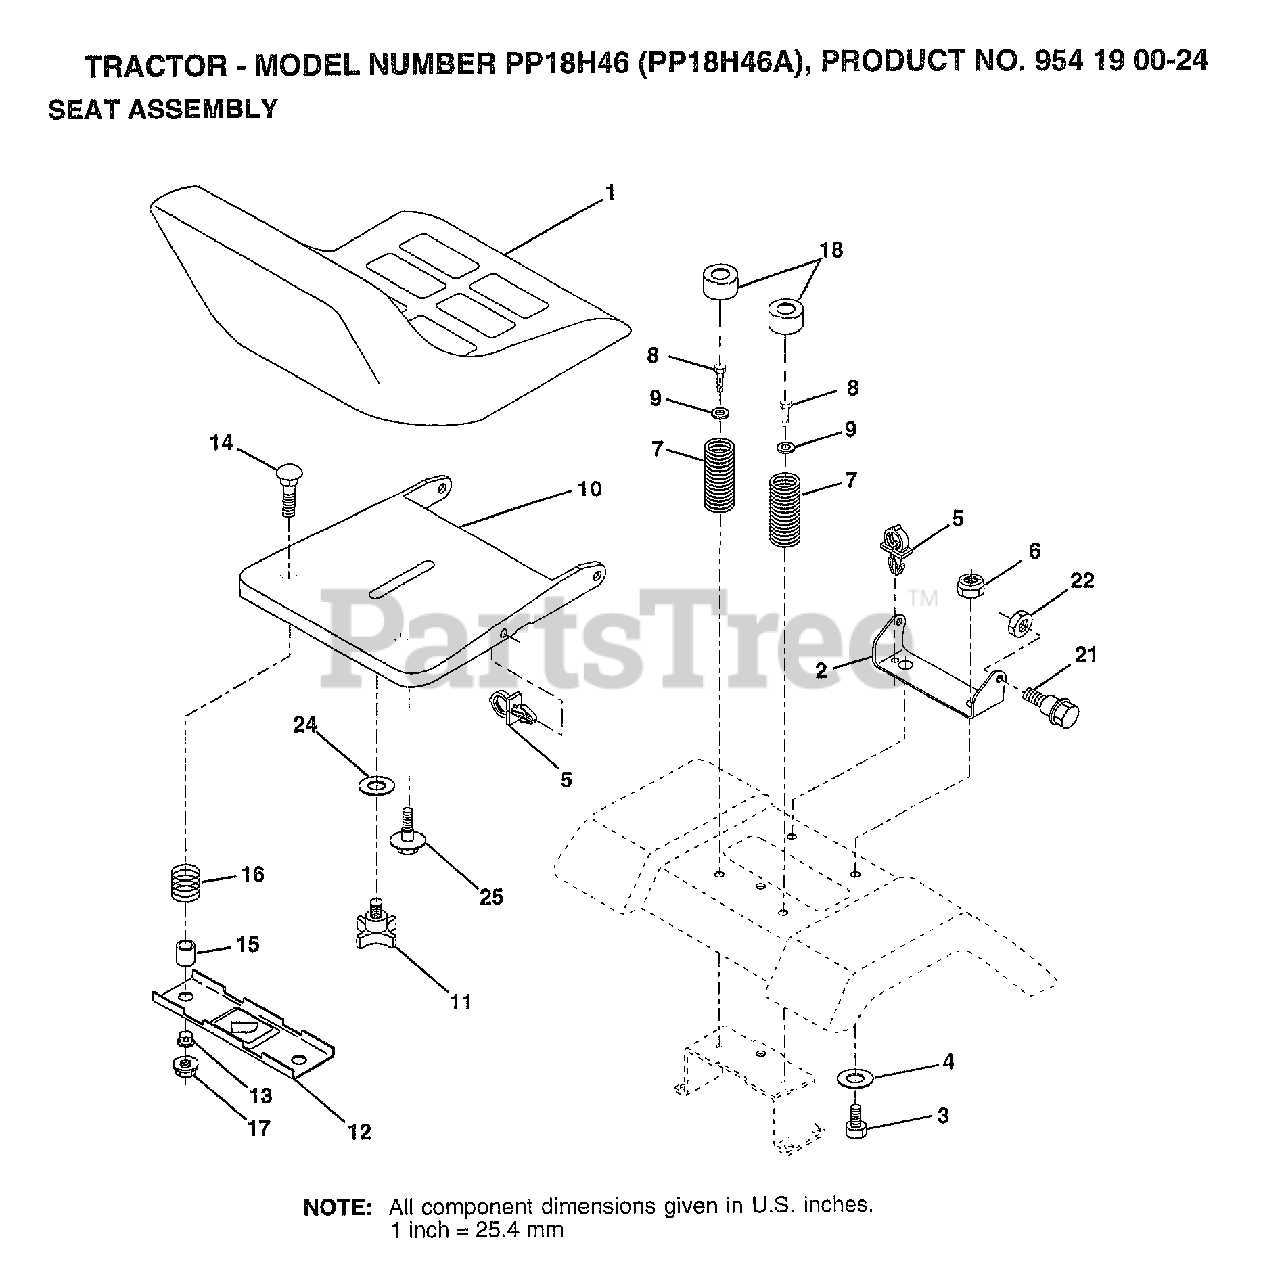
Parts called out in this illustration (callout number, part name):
1	SEAT.2500/1516.BK
2	BRACKET PVT SEAT
3	BOLT
4	WASHER PM
5	CLIP.PUSH-IN.HING
6	NUT
7	SPRING, COMPRESSION, SEAT
8	SCREW GTV
9	WASHER
10	PAN-SEAT
11	"KNOB 1/2"" YT"
12	BRKT SWITCH
13	BUSHING
14	BOLT-RD HD SQ NK
15	SPACER SPLIT
16	SPRING COMPRESSED
18	CAP SPRING
21	"BOLT,SHOULDER"
22	NUT
24	WASHER
25	"BOLT,SHOULDER"
